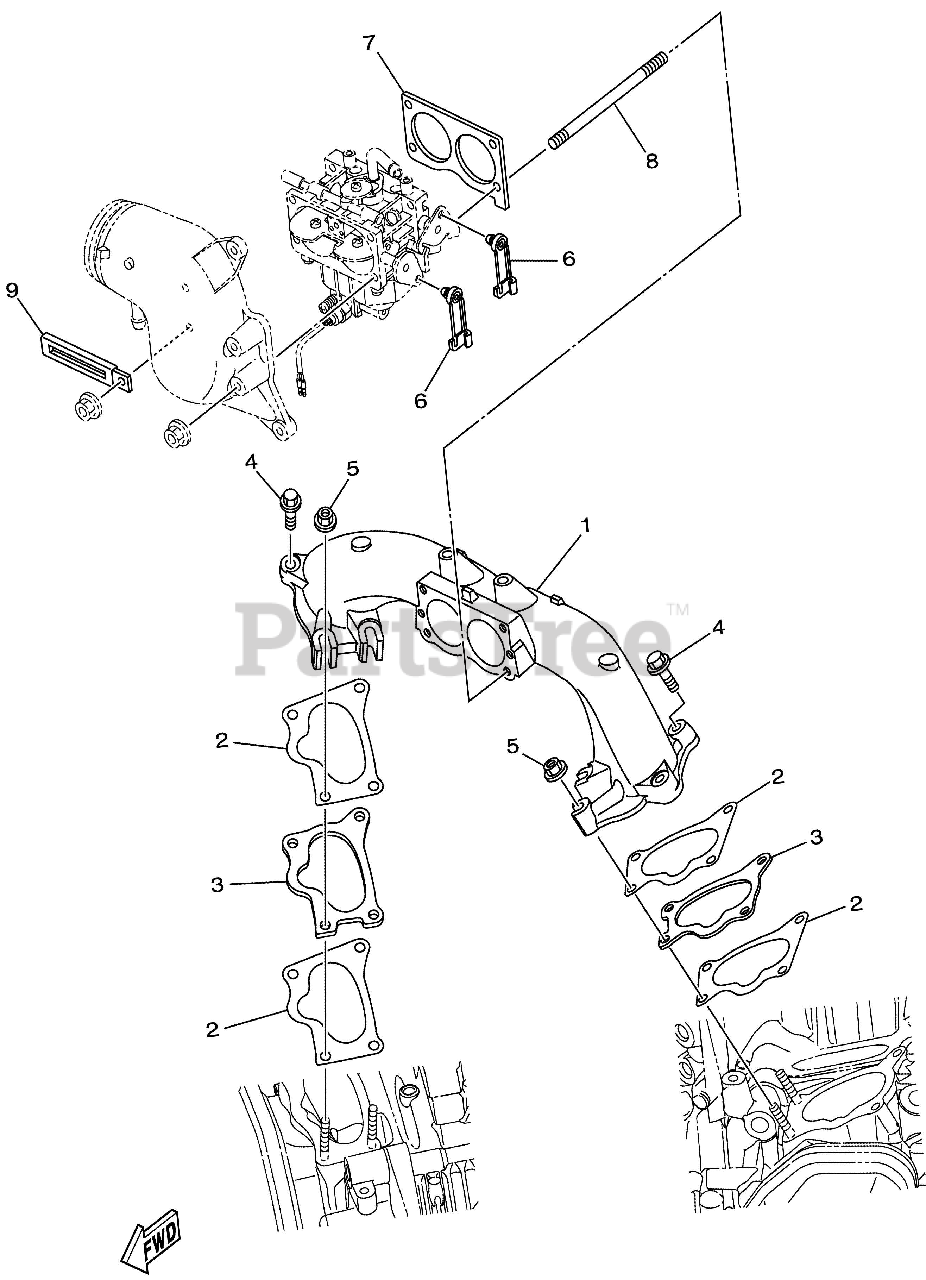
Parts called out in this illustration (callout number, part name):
1	MANIFOLD
3	JOINT, CARBURETOR 1
4	BOLT, FLANGE
5	NUT, FLANGE
6	BOSS, ROD END
7	GASKET, MANIFOLD 1
8	BOLT, STUD
